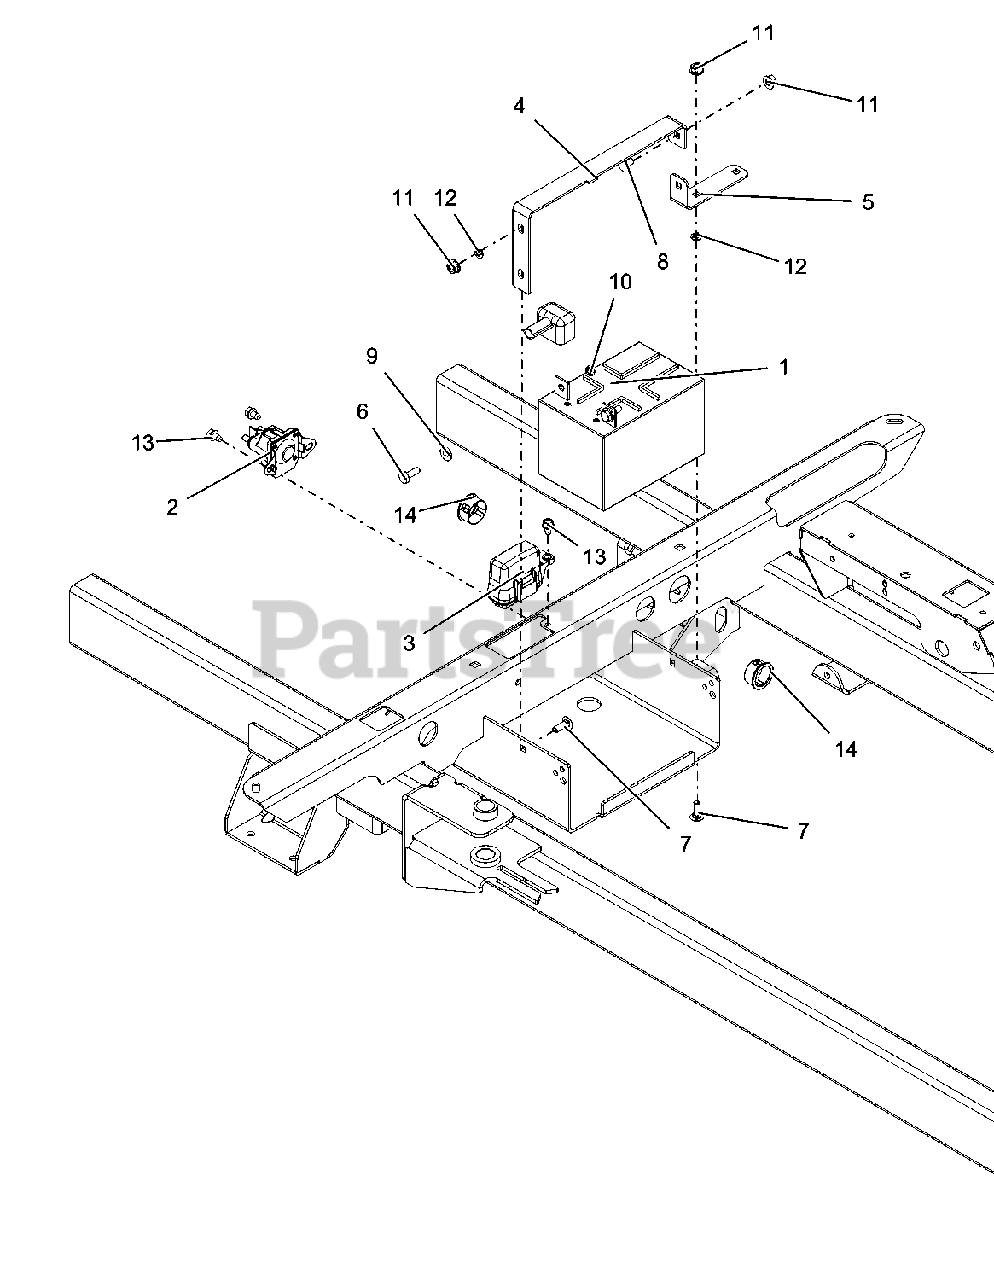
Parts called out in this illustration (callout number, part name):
1	BATTERY, 12V 12A -190CCA
2	SOLENOID, STARTER (SEALED)
3	HARNESS, WIRE -2015 ZOOM/ZT
4	BRKT, BATTERY HOLD-DOWN
5	BRKT, BATTERY (BLACK)
6	BLT-HEX .25-20X.75 GR5 YWZC
7	BLT-RDHDSQNK .25-20X.75 G5 YWZC
8	BLT-RDHDSQNK .25-20X.50 G5 Y
9	WSHR-FL-STL.281X.62X.065 YWZC
10	NUT-KEPS 10-24
11	NUT, LK-TOP-FLG .25-20 YWZC
12	NUT, PUSH .25X.50 O.D.
13	SCR-TAP .25-20X.37 HWH YWZ TR
14	BSHG, PANEL SNAP .937X1.109X.56
